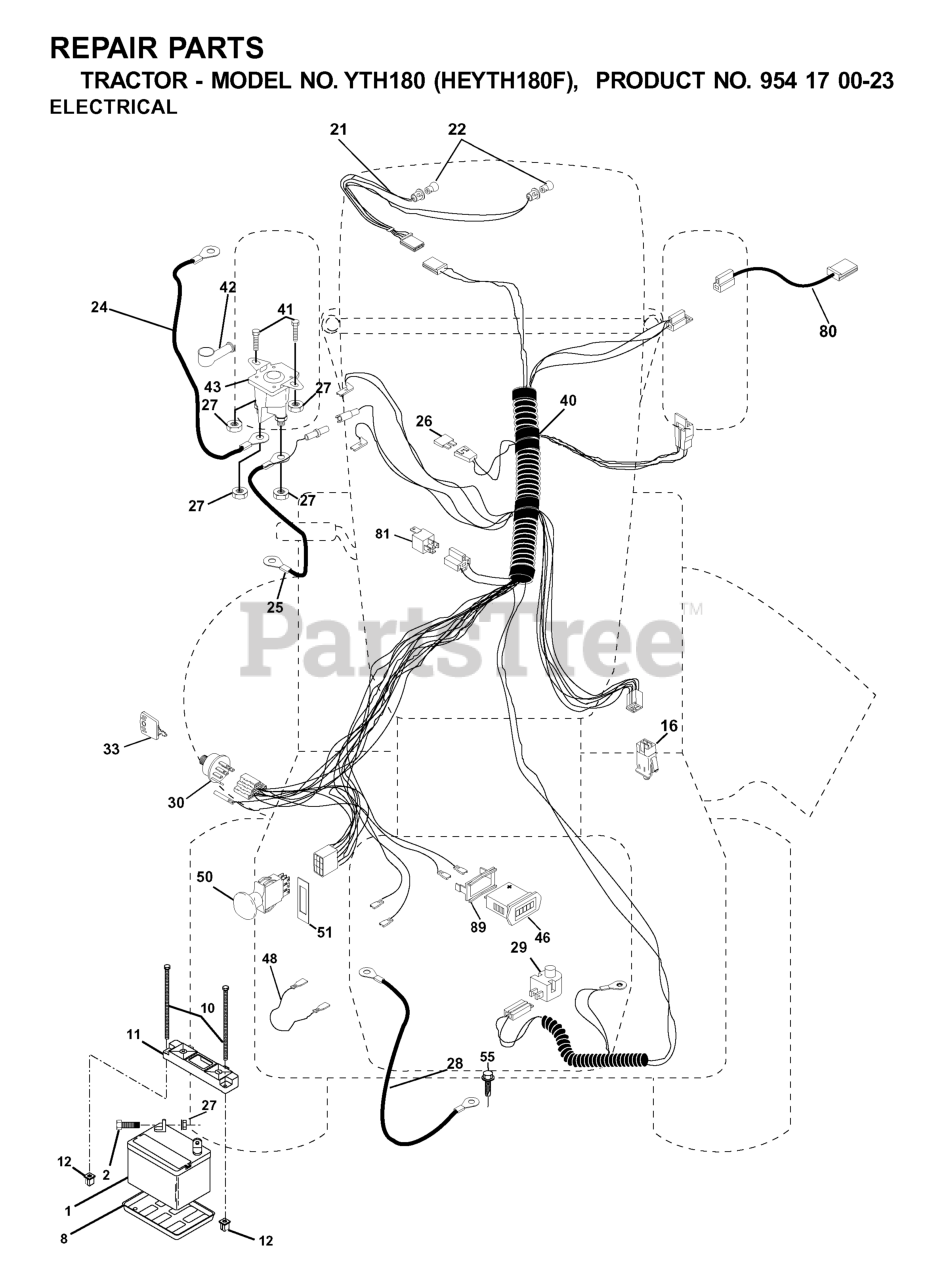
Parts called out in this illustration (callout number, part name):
1	Battery 12 Volt 25 Amp
2	BOLT.HEX.1/4.X.3/4.DICHROMATE
8	BATTERY TRAY T
10	BOLT 1/4-20 X 7.5
11	BATTERY HOLDDOWN FRONT MOUNT
12	NUT, PUSH NYLON 1/4" BATTERY
16	SWITCH INTERLOCK
24	BATTERY CABLE GT
25	CABLE BATTERY 6 GA 22" W/16W
26	FUSE 20AMP
27	NUT
28	CABLE GROUND 6 GA 21" 90T BLK
29	PLUNGER SWITCH (COLOR:OLIVE)
30	IGNITION SWITCH
33	KEY MLD GEN DELTA
40	HARNESS IGN.
41	BOLT
42	TERMINAL COVER
43	REPL BY 532 1461-54
46	HOUR METER
48	ADAPTER.AMMETER
50	RP.PTO.SWITCH.8 TERMINAL.BLACK
51	FRAME RETAINING RING
55	Screw 5/16-18 x 1/2 Hex, Self Tapping 5/16-18 x 1/2
80	HARNESS, CLUTCH
81	RELAY.ASSY.T
89	BRACKET SNAP-IN HOURMETER
